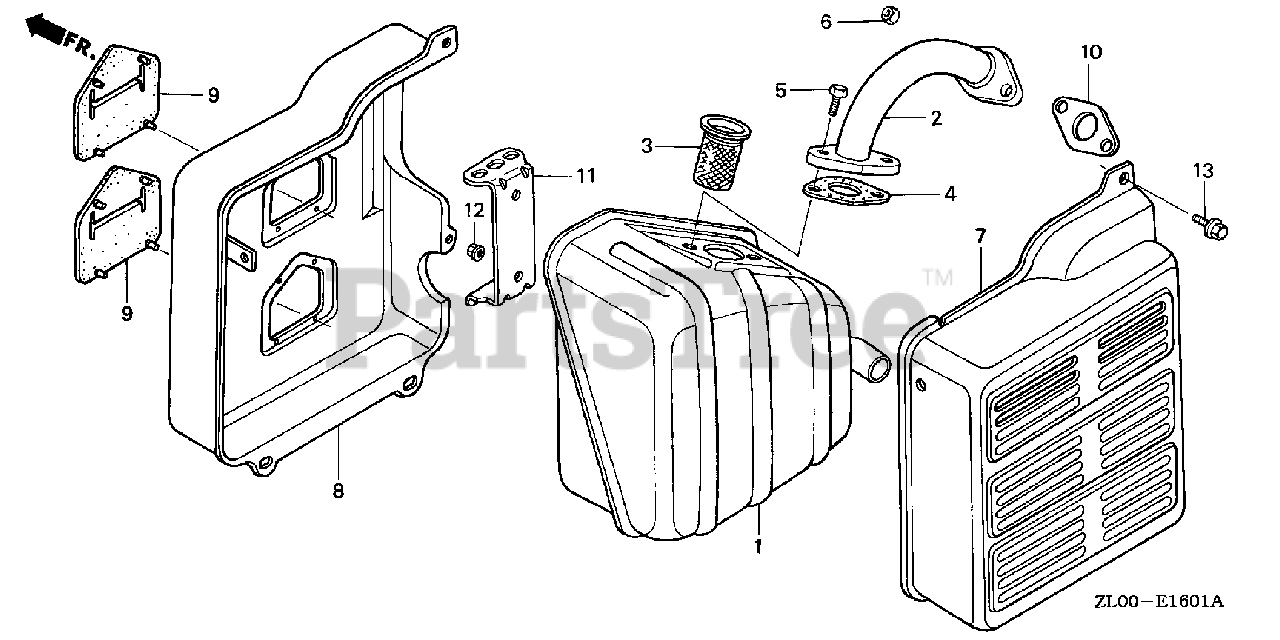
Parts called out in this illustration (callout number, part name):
1	MUFFLER
2	PIPE, EX.
4	GASKET, MUFFLER
5	BOLT, HEX. (8X20)
6	NUT, HEX. (8MM)
7	PROTECTOR, MUFFLER (OUTER)
8	PROTECTOR, MUFFLER (INNER) (DENYO)
9	SEAL, MUFFLER PROTECTOR
10	GASKET, MUFFLER
11	STAY, MUFFLER
13	BOLT, FLANGE (6X12)
